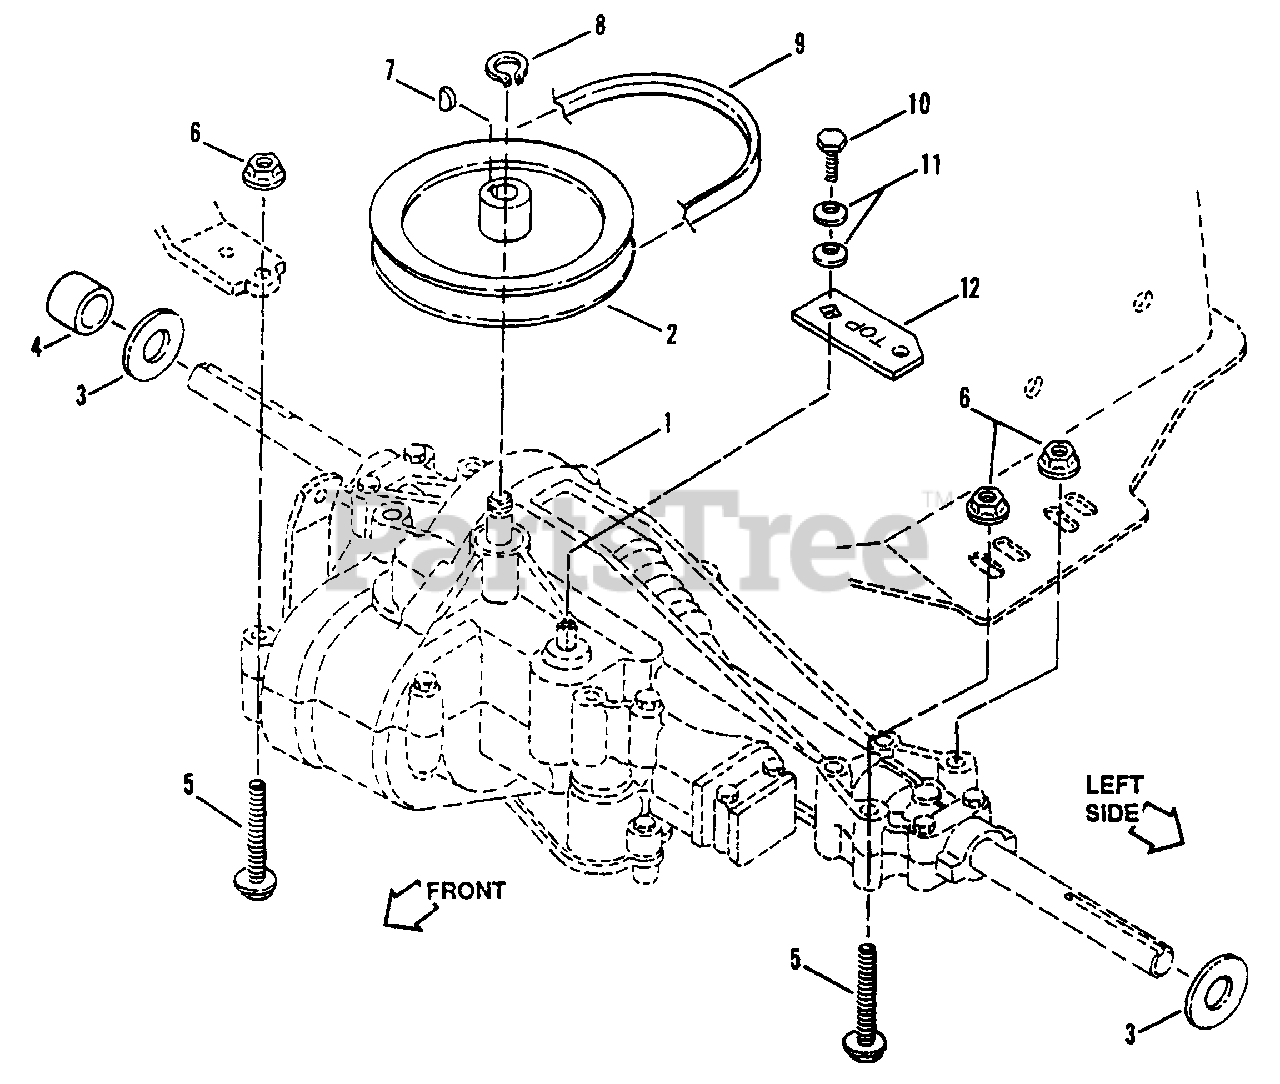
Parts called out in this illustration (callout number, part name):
1	TRANSAXLE ASSEMBLY
2	PULLEY, Drive
3	WASHER, Flat
5	BOLT, 5/16-18 x 2 1/4" Hex Range Lock
6	NUT, 5/16-18 Hex Flange Lock
7	KEY, Woodruff
8	RING, Retaining
9	BELT, P915, Traction Drive, 97.08" EL
10	BOLT, 1/4-28 x 5/8" Hex Head, Grade 8
11	WASHER, Bellville
12	ARM, Shift Input
